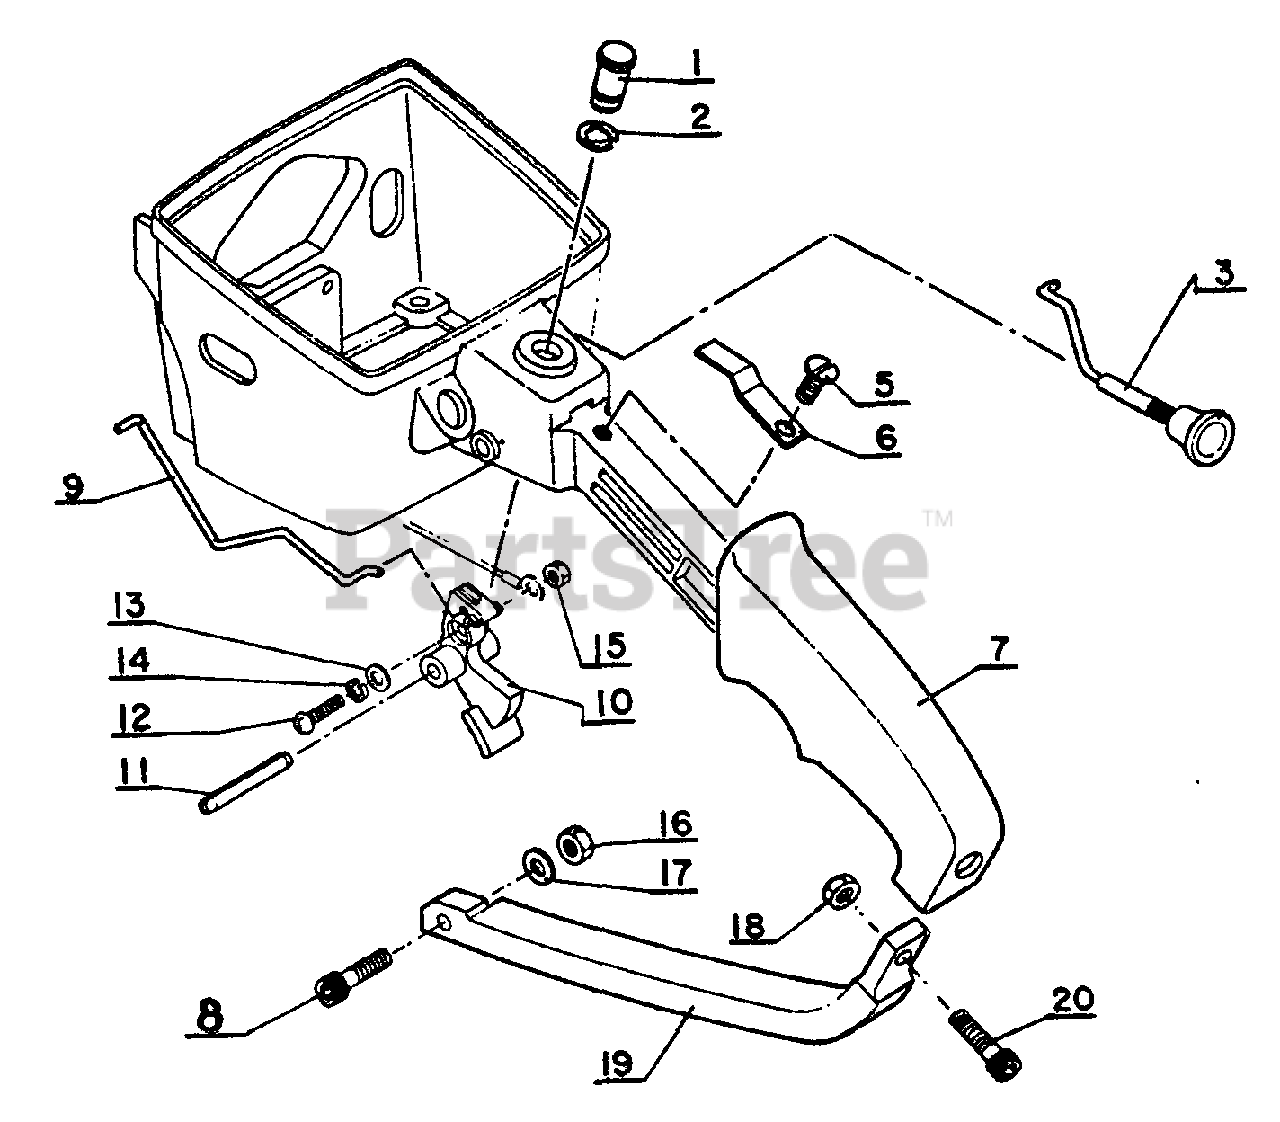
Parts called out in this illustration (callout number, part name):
1	LOCKOUT, THROTTLE
2	RING, RETAINING - 6
3	ROD, CHOKE
5	SCREW - 5×6
6	LEAF SPRING
7	RIGHT HANDLE RUBBER
8	BOLT 5×25
9	ROD, THROTTLE
10	TRIGGER, THROTTLE
12	SCREW 4×12
13	WASHER 4 MM
14	WASHER, SPRING 4 MM
16	LOCKNUT - 5
17	WASHER, FLAT 5.5×10×0.8
18	NUT M5
19	RIGHT HANDLE SUPPORTER
20	BOLT 5×25
